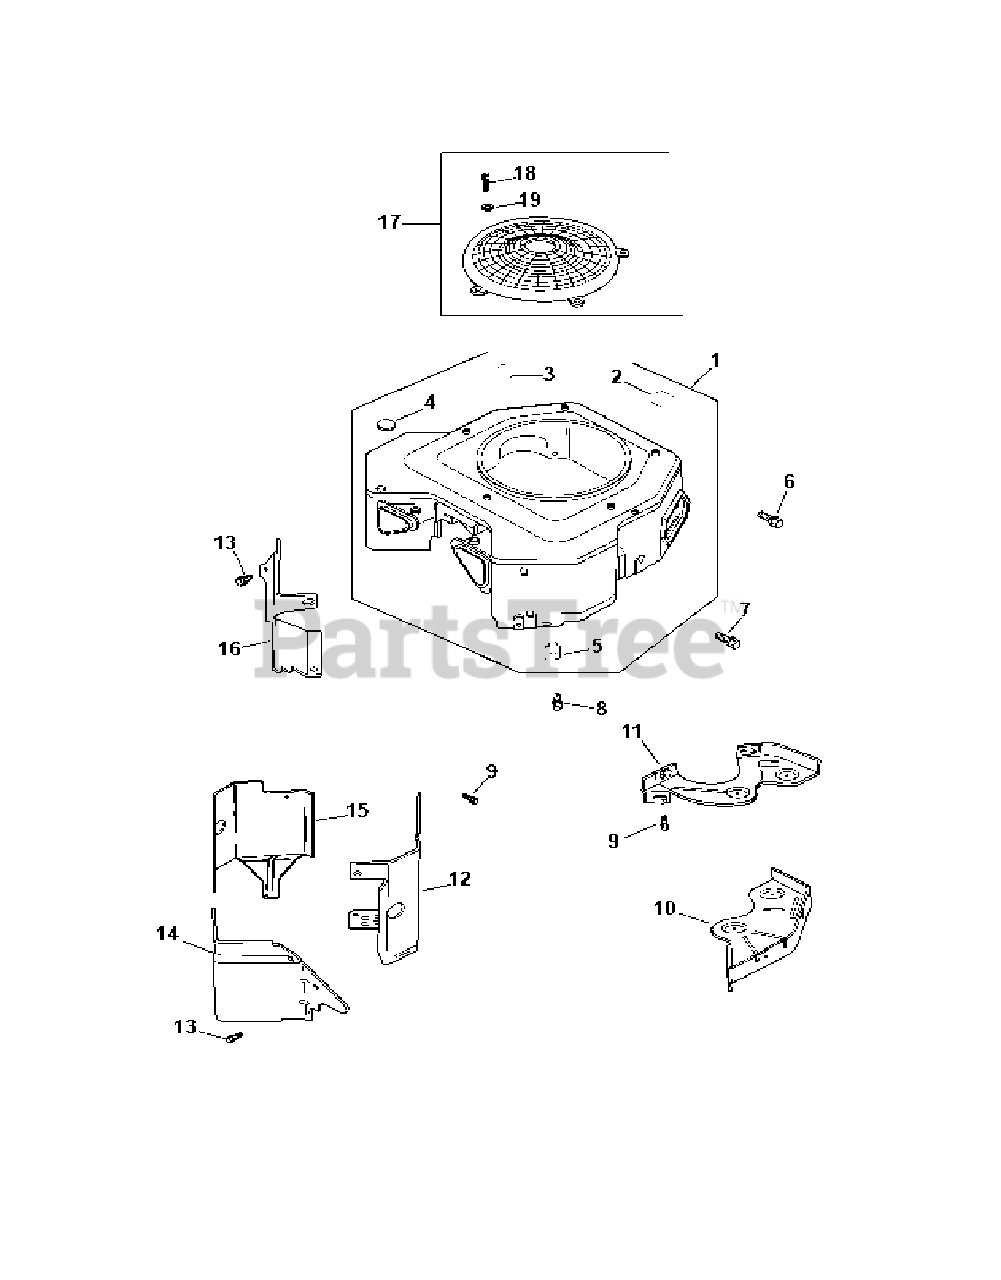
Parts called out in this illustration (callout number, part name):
1	Blower Housing
2	Plastic Nut
3	Tapping Screw
4	9/16" Button Plug
6	Screw
8	Screw
10	Backing Plate # 2
11	Backing Plate # 1
12	Cylinder Barrel Baffle # 2 Side
14	Valley Baffle # 2 Side
15	Cylinder Barrel Baffle # 1 Side
16	Valley Baffle # 1 Side
17	Fixed Guard Kit
18	Pan Head Screw
